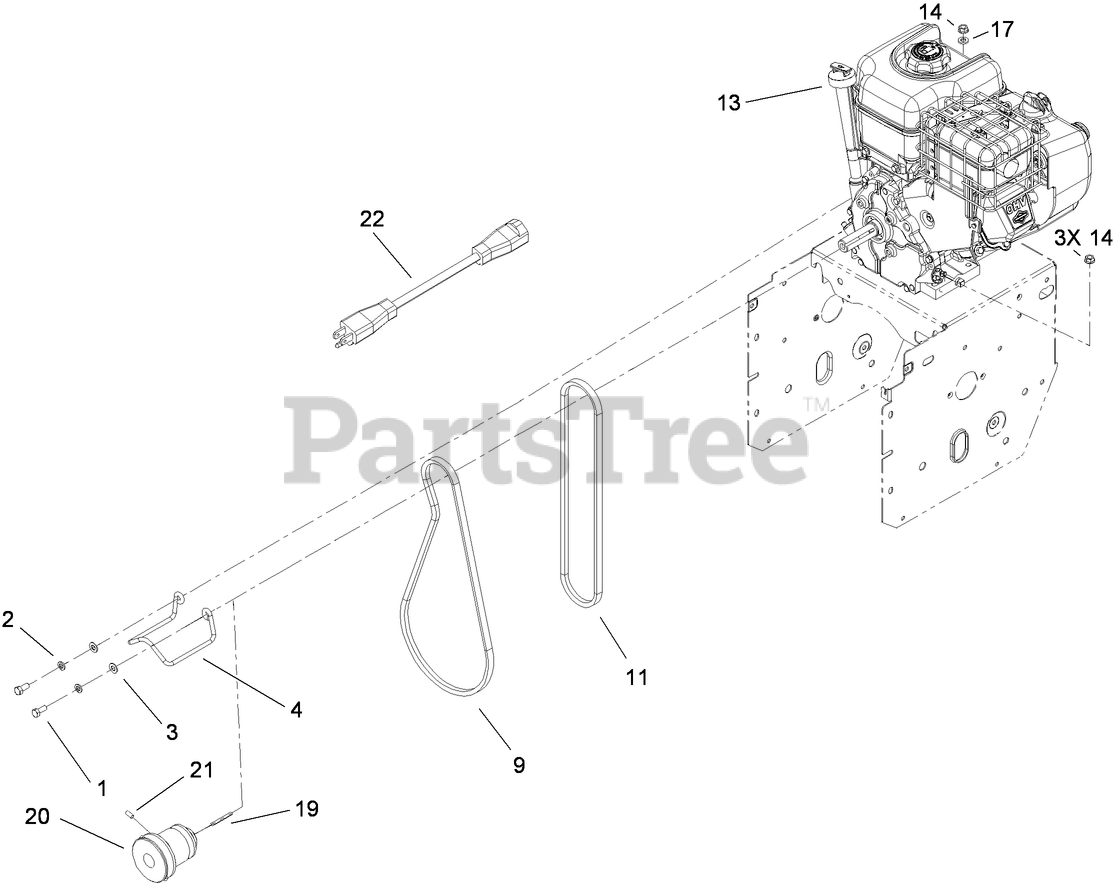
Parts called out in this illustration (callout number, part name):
1	SCREW-HH
2	WASHER-LOCK
3	WASHER-PLAIN
4	GUIDE-BELT
9	BELT-V
11	V BELT-TRACTION
14	NUT-HF
17	WASHER-FLAT
19	KEY-SQUARE
20	PULLEY-ENGINE
21	SCREW-SET, HSH
22	CORD-EXTENSION
